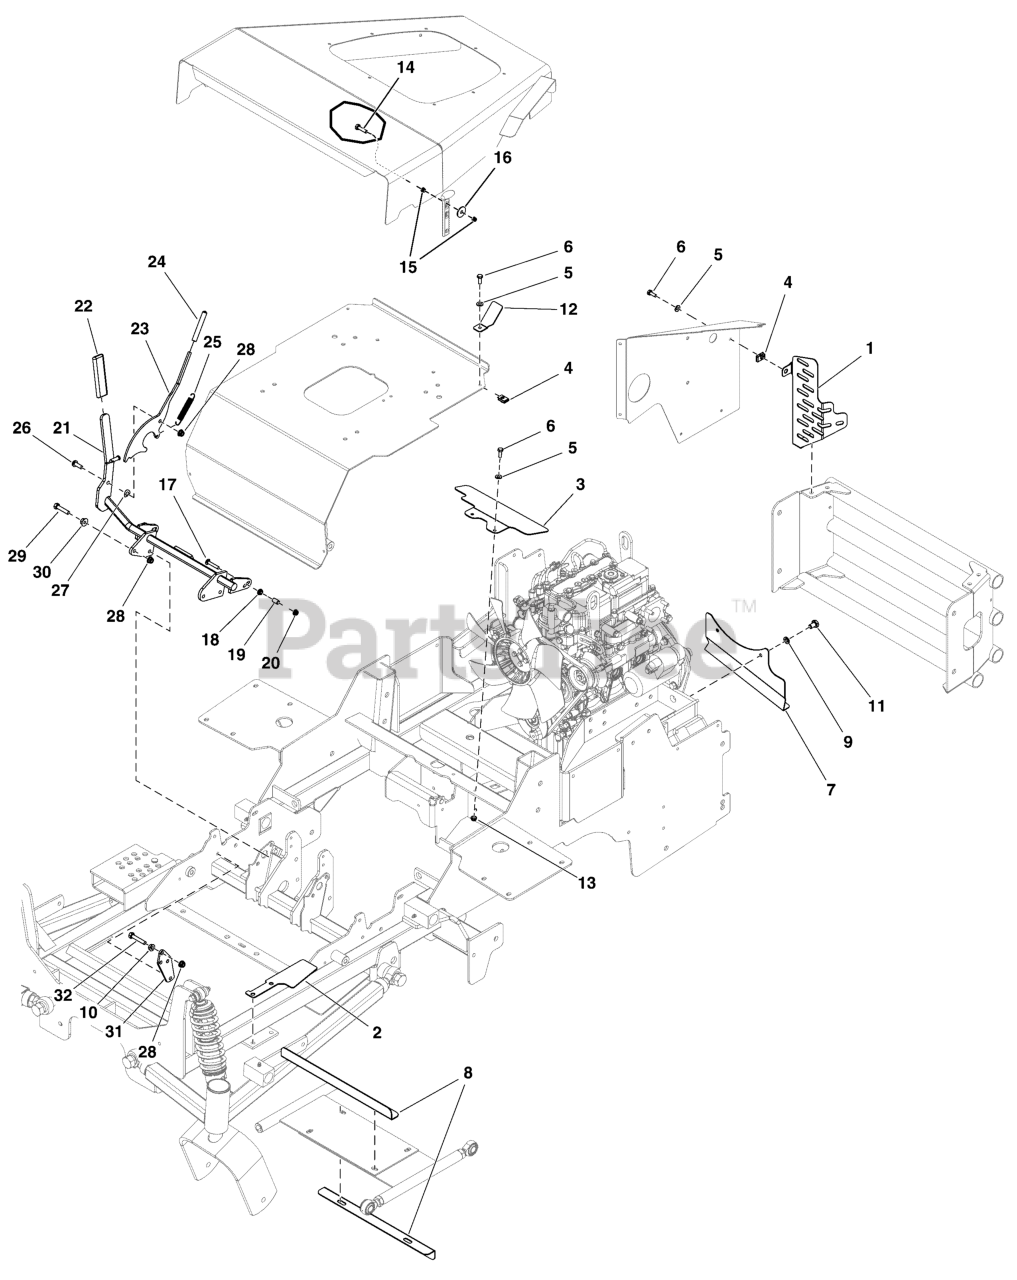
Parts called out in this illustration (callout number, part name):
1	PLATE, GUARD, FLY WHEEL, IS2600Z EU, RED
2	PLATE, DECK SHIELD, FRAME - LH - RED
3	PLATE, SEAT GUARD, REAR, CE - RED
4	BODY CLIP, 1/4-20 X 1/2" DEEP
5	WASHER, 1/4 SAE
6	BOLT, 1/4"-20 X 3/4" GD5 YZ
7	PLATE, POWER HEAD BELT GUARD - RED
8	PLATE, GUARD, PULLER BAR,IS2600Z EU, BLK
9	WASHER, 5/16 LOCK CZ
10	NUT, 5/16-18 HEX SERRATED FLANGE (SMALL)
11	BOLT, M10-1.5 X 16MM GD8.8
12	PLATE, LATCH LOCKOUT, CE - BLK
13	NUT, 1/4-20 Hex Nylock Flange
14	SCREW, 8-32 X 3/4, HEX SERR FLG. GR5, CZ
15	NUT, #8-32 Hex Nylon Lock
16	WASHER, FENDER, #10 X 1-1/4"OD, SS
17	BOLT, 1/4-20 X 1.500, GR5, SQ, ZINC/CLEAR
18	NUT, 1/4-20 HEX SERR. FLANGE
19	SPACER, .52 X .38 X .63, CZ
20	NUT, 1/4-20 Hex Nylock Flange
21	WELD, HANDLE, BRAKE, IS2600 CE - BLK
22	GRIP, FOAM, 1/4 X 1 X 4.1
23	LEVER, BRAKE, IS2600 EU - BLK
24	COVER, VINYL HANDLE
25	SPRING-EXT, .500 OD X 3.50 LG X .058 WR
26	SCREW, TRUSS HD TORX DR5/16-18X0.875 BLK
27	WASHER,WAVE,M10
28	NUT, 5/16-18 HEX NYLOCK FLANGE NUT
29	BOLT, 5/16-18 X 1-1/2" GD5 YZ
30	NUT, 5/16-18 HEX SERRATED FLANGE (LARGE)
31	PLATE, PIVOT MOUNT, BRAKE,IS2600 EU, RED
32	BOLT, 5/16-18 X 1-3/4" GD5 YZ
